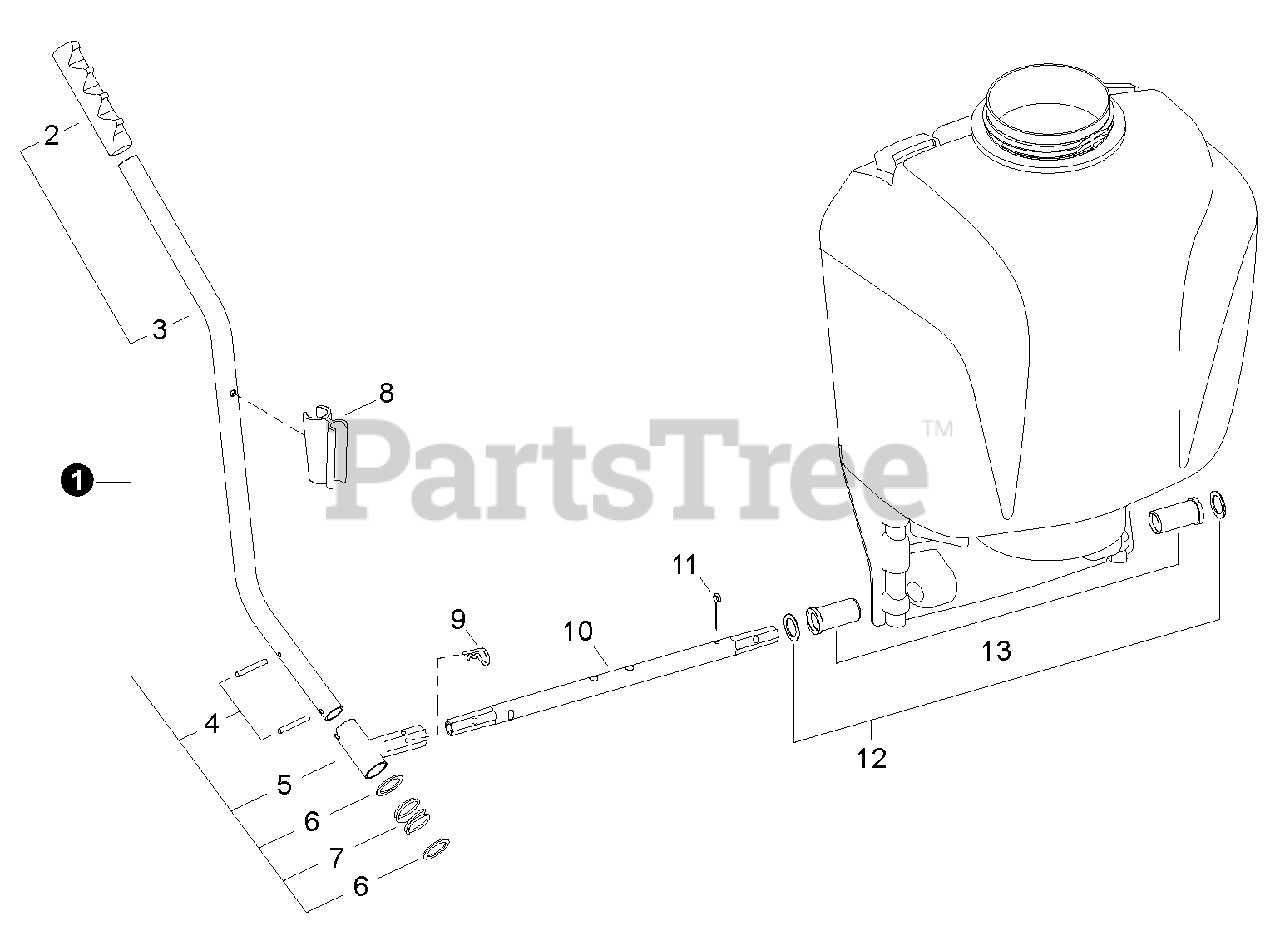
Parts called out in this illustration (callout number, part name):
1	LEVER KIT, PUMP
2	GRIP, LEVER
3	LEVER, PUMP
4	PIN, METERING LEVER
5	BRACKET, LEVER
6	WASHER
7	SPRING, METERING LEVER
8	CLIP, WAND
9	PIN, COTTER
10	SHAFT, PUMP
11	PIN, SHAFT
12	WASHER, SHAFT
13	BUSHING, SHAFT
